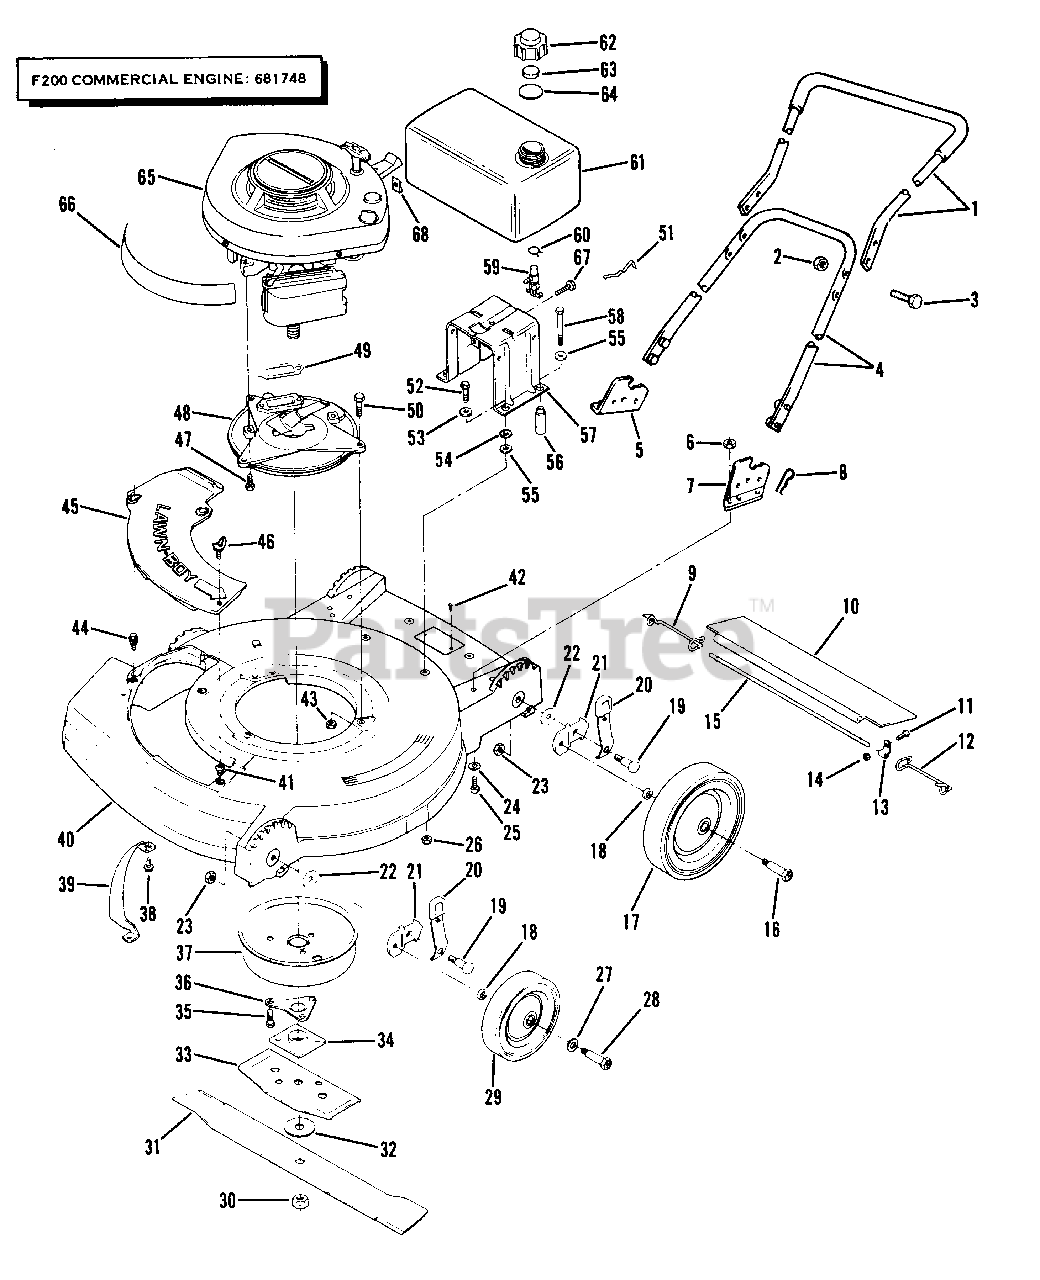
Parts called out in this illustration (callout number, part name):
1	Top Handle & Grip Assembly
2	Nut-Handle Bracket
3	Screw-Handle
4	Handle-Bottom & Pin Assembly
5	Handle Bracket-R.H.
6	Nut-Handle Bracket
7	Handle Bracket-L.H.
8	Hair Pin
9	Spring-R.H.
10	Shield-Trailing
11	Screw-Clamp
12	Spring-L.H.
13	Clamp
14	Nut
15	Rod-Trailing Shield
16	Bolt-Rear Wheel
17	Wheel & Tire Assembly-Rear
18	Washer-Wheel Bolt
19	Shoulder Bolt
20	Knob & Spring Assembly
21	Bracket-Wheel Height Adjustment
22	Washer
23	Nut
24	Washer-Handle Bracket Mounting
25	Bolt-Handle Bracket to Housing
26	Nut-Tank Mounting
27	Washer-Front Wheel Bolt
28	Bolt-Front Wheel
29	Wheel & Tire Assembly-6"
30	Nut-Blade
31	Blade-21"
32	Washer-Blade
33	Stiffener-Blade
34	Collar & Plate Assembly
35	Screw
36	Support-Crankshaft
37	Muffler Cover Assembly
38	Screw-Sems
39	Toe Bar
40	Housing-21"
41	Grommet
42	Screw-Model Plate
43	Nut-Muffler Plate to Housing
44	Screw-Sems-Plate Mounting
45	Cover Plate
46	Wing Screw
47	Screw-Muffler Plate to Block
48	Plate-Muffler
49	Gasket-Exhaust
50	Screw-Muffler Plate to Housing
51	Spring-Fuel Tank Mounting
52	Screw
53	Washer
54	Grommet-Tank Mounting
55	Washer-Tank Mounting
56	Spacer-Fuel Tank Mounting
57	Bracket-Fuel Tank
58	Bolt-Tank Mounting
59	Shut-Off Valve & Screen
60	Clamp
61	Fuel Tank
62	Fuel Cap
63	Gasket
64	Baffle
65	Engine-Model F 200 Commercial
66	Decal-Lawn-Boy
67	Screw-Tank Bracket to C.D. Bracket
68	Speednut-C.D. Bracket
